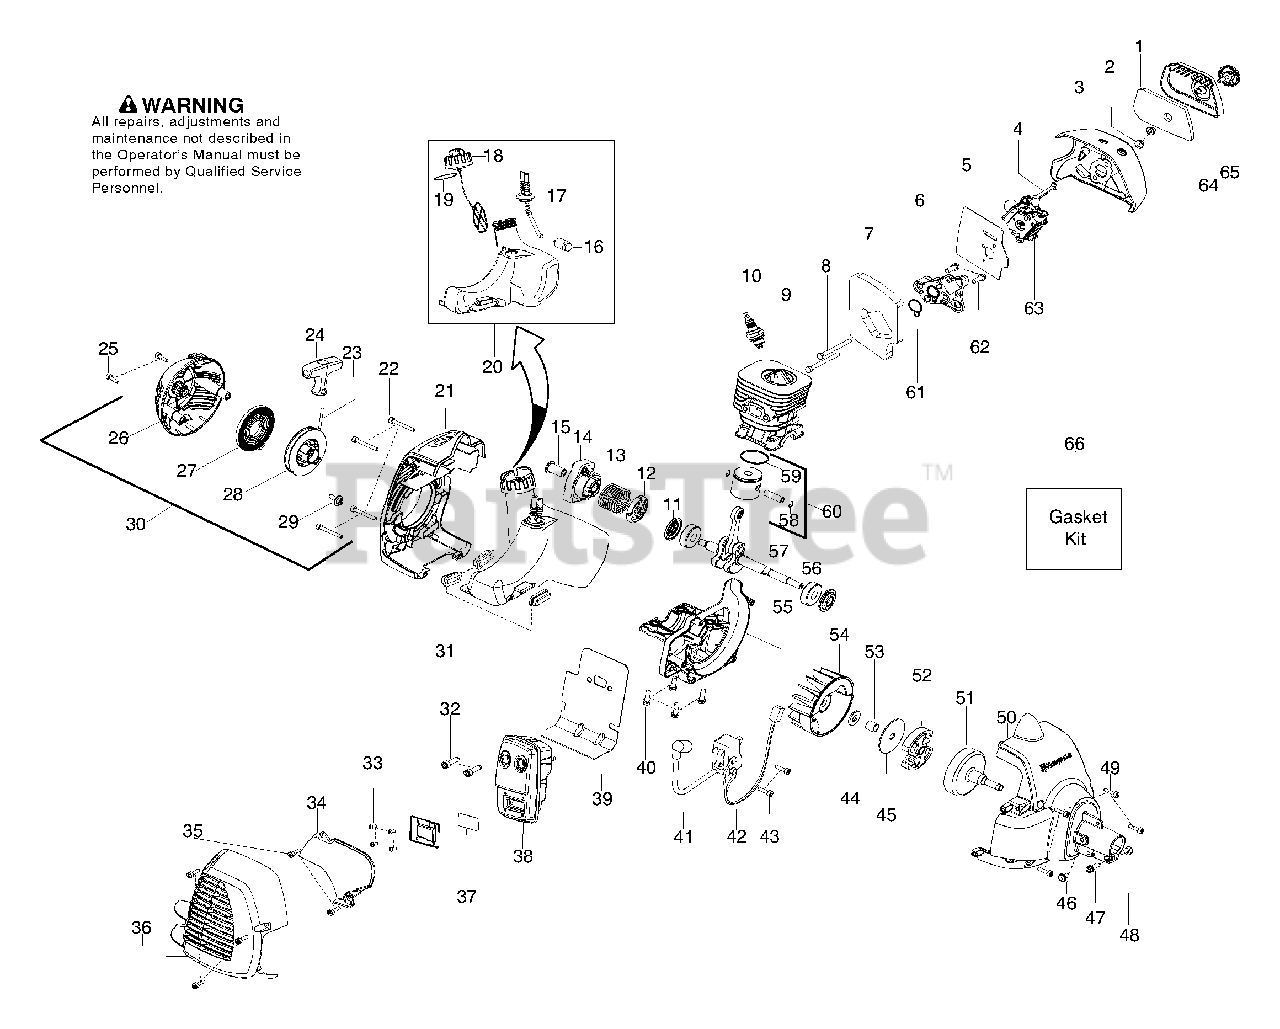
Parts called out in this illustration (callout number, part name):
2	Nut-Carb Screw
3	Air Box
4	Lever-Choke
5	Kit-Carb Gasket
6	Adaptor-Carb
7	Kit-Gasket (foam)
9	Cylinder
10	Plug-Spark (RCJ-8Y)
11	Kit-Crankshaft seal
12	Washer-Starter
13	Spring-Starter Cup
14	Assy-Starter Cup
15	Coupling-Starter
16	Assy-Fuel Filter
17	Kit-Fuel Line
18	Assy-Cap w/ret
19	O-ring - Fuel Cap
20	Assy-Fuel Tank
21	Shroud-Rear
24	Handle-Starter
26	Starter Hsg w/eyelet
27	Kit-Starter Spring
28	Kit-Starter Pulley
30	Assy-Starter Hsg
31	Isolator-Tank
32	Bolt-Muffler
34	Shield-Heat
36	Guard-Muffler
37	Kit-Spark Arrestor
38	Assy-Muffler
39	Gasket-Paper Metal
42	Assy-Leadwire
45	Washer-Clutch
50	Assy-Fan Housing
51	Assy-Clutch Drum
52	Kit-Clutch Assy
55	Crankcase-Machined
57	Kit-Crankshaft
58	Retainer-Piston Pin
59	Ring-Piston
60	Kit-Piston
61	Kit-Gasket (adaptor seal)
63	Kit-Carb
64	Cover-Air Box
66	Kit-Gasket
